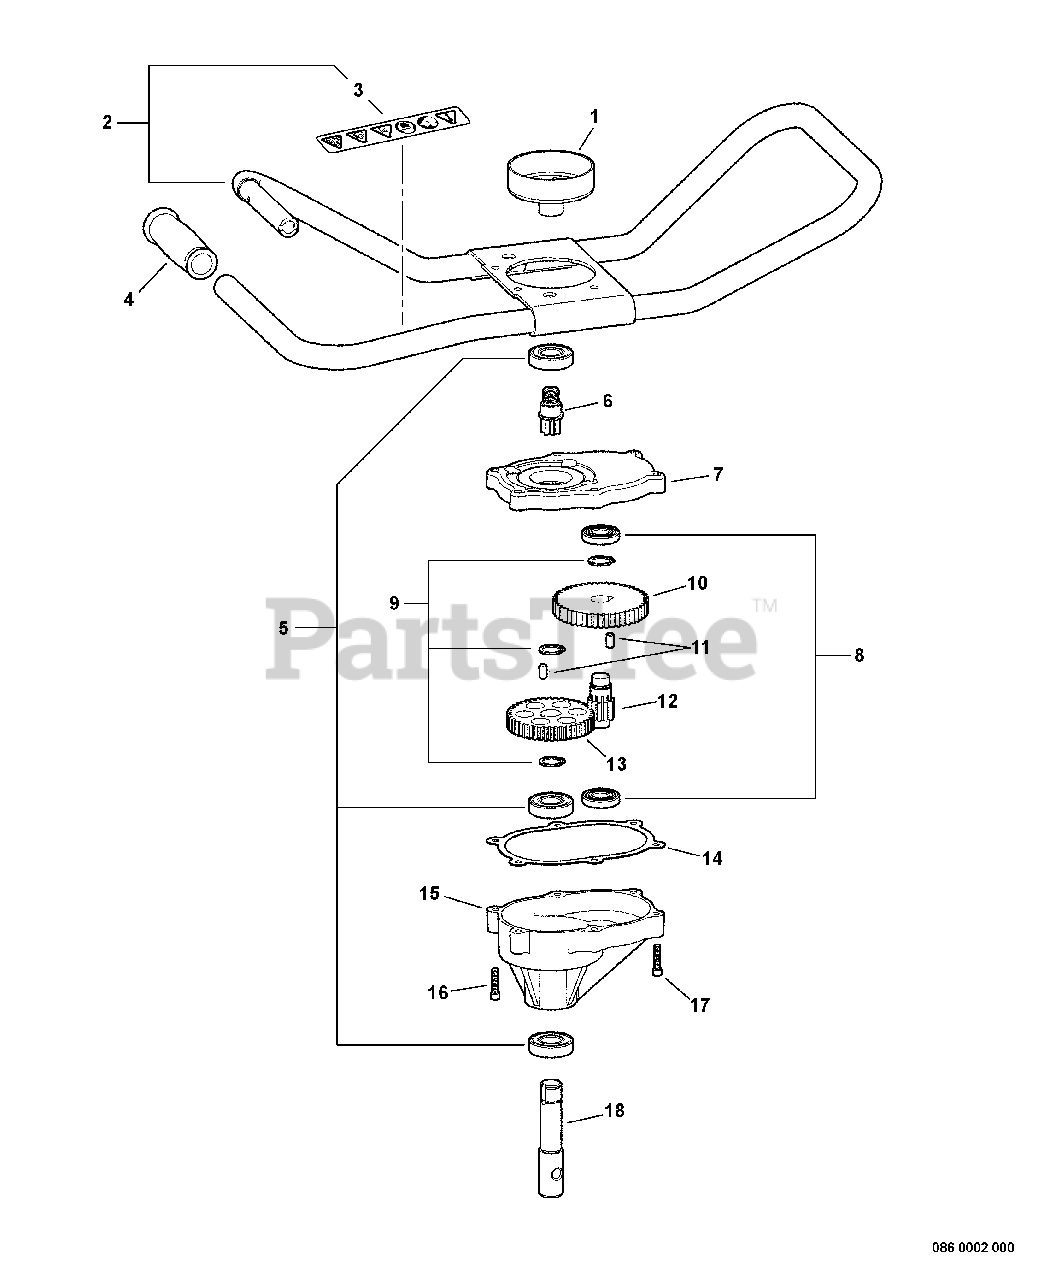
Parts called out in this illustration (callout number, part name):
1	DRUM, CLUTCH
2	HANDLE BAR ASSY
3	LABEL - CAUTION
4	GRIP, HANDLE
5	BEARING, BALL
6	GEAR - SHAFT
7	CASE, GEAR - UPPER
8	BEARING, BALL
9	RING, RETAINING
10	GEAR - SPUR
11	PIN - LOCATING
12	GEAR - SHAFT
13	GEAR - SPUR
14	GASKET, GEAR CASE
15	CASE, GEAR - LOWER
16	BOLT - 1/4-20 X 2"
17	BOLT - 1/4-20 X 1-1/2"
18	DRIVESHAFT
